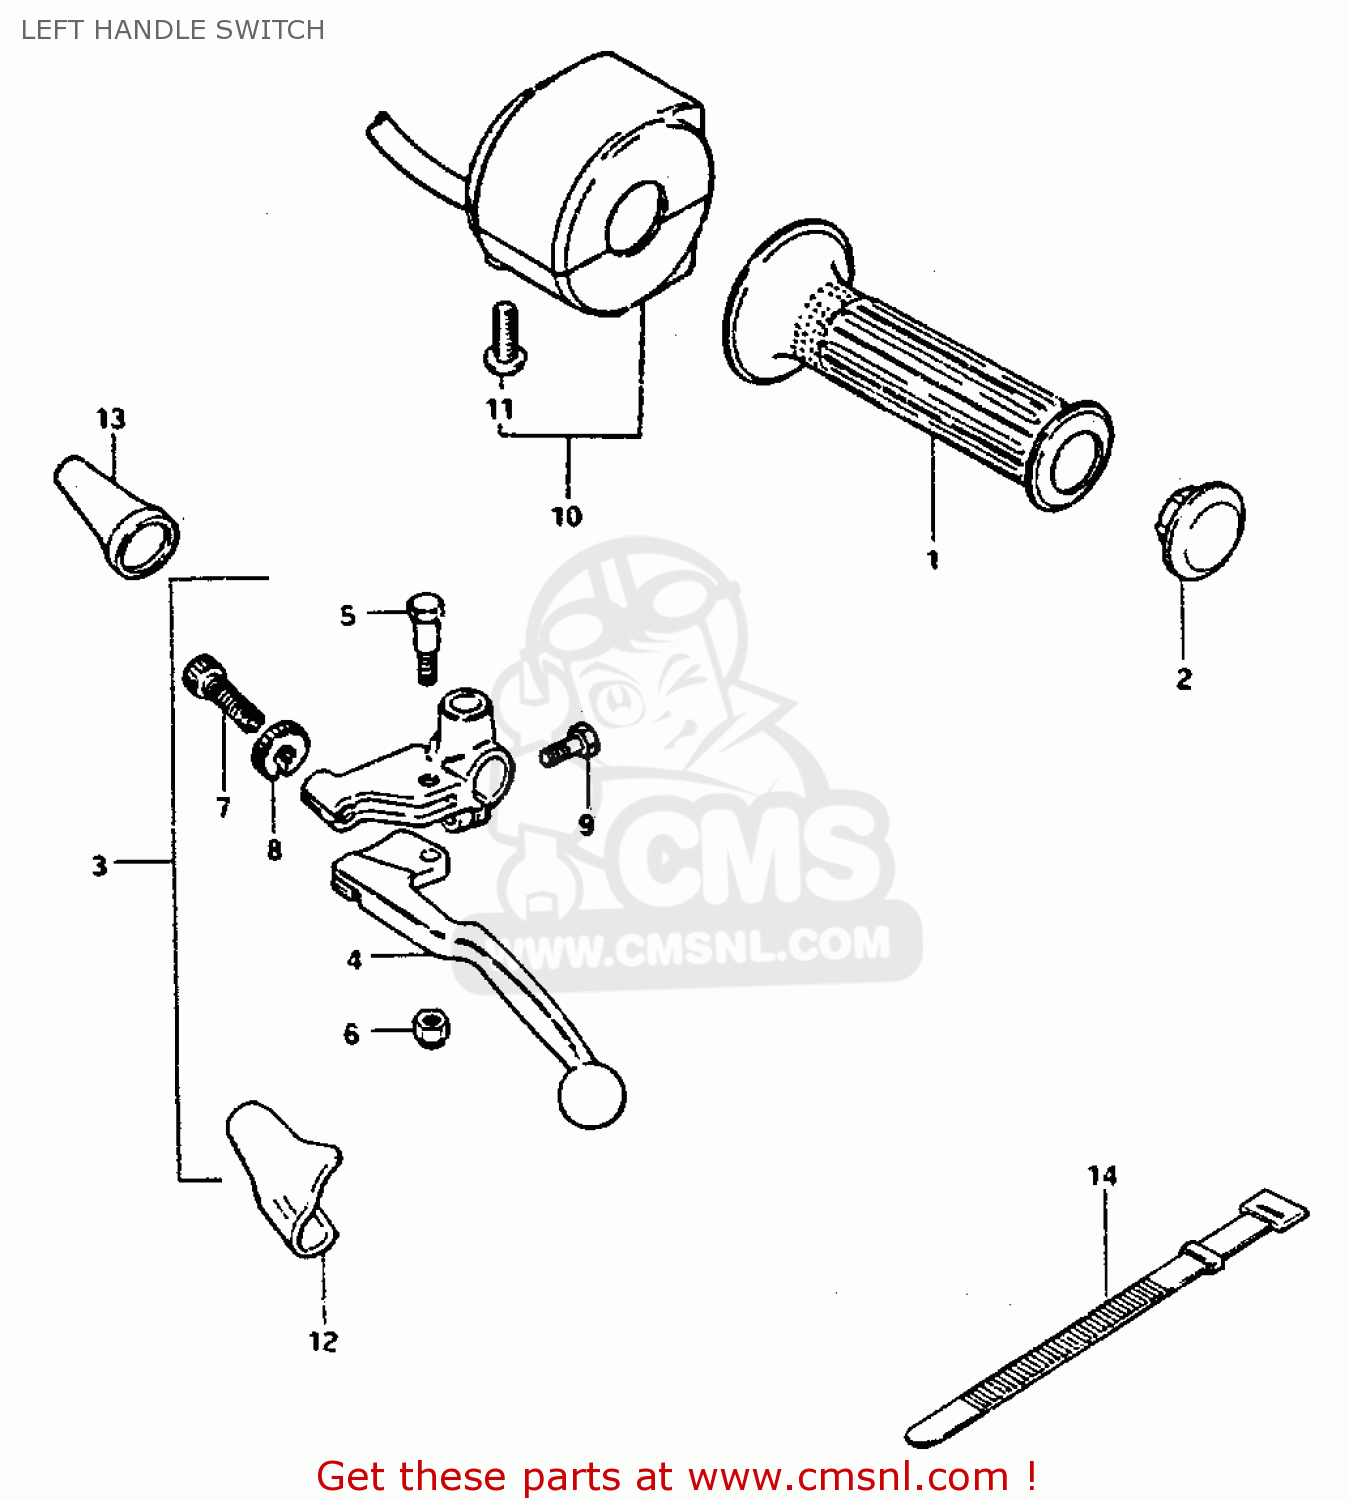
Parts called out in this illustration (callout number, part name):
1	GRIP,LEFT
2	CAP,GRIP END
3	LEVER ASSEMBLY
4	LEVER,CLUTCH
5	BOLT,LEVER
6	NUT 6MM
7	ADJUSTER,CABLE
8	NUT,CABLE ADJUSTER
9	BOLT
10	SWITCH ASSY, HANDLE LH
11	SCREW
12	COVER,CLUTCH LEVER
13	BOOT,CLUTCH CABLE
14	CLAMP(L:120)
